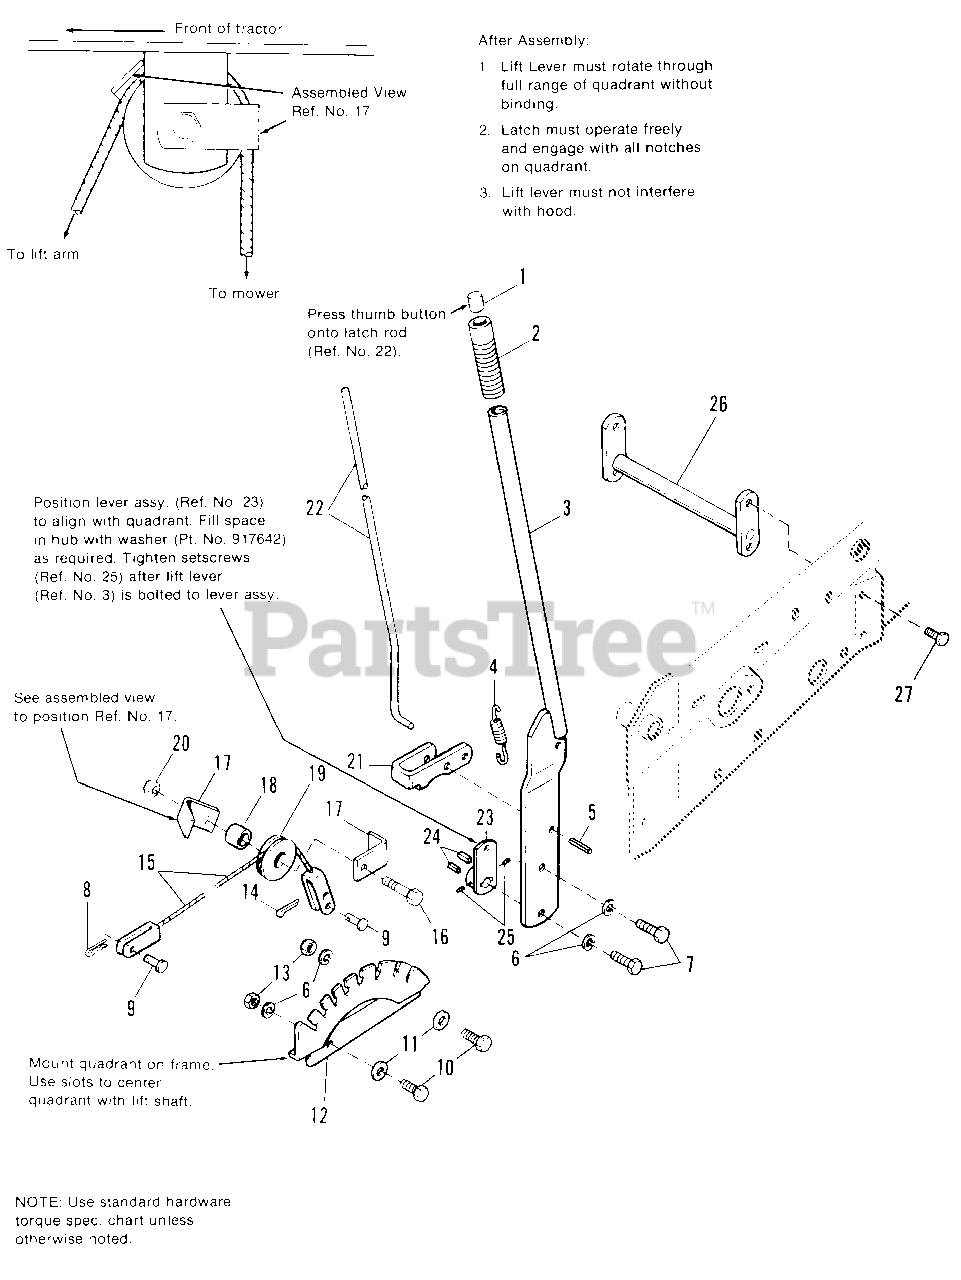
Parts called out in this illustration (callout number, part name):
2	GRIP
3	LEVER ASSY., Lift
5	PIN, Spring, 3/8 x 1-1/4
6	LOCKWASHER, 3/8
7	CAPSCREW, Hex Hd., 3/8-16 x 1
8	CLIP, Spring
10	CAPSCREW, Hex Hd., 3/8-16 x 7/8
11	WASHER, Plain, 5/16
13	NUT, Hex, Full, 3/8-16
14	PIN, Cotter, 3/32 x 3/4
15	CABLE ASSY., Lift
16	SCREW, Special
17	GUARD, Cable
20	LOCKNUT, Hex, Jam, 3/8-16
21	LATCH, Lift Lever
22	ROD LATCH
23	LEVER ASSY., Lift
25	SETSCREW, 5/16-18 x 1/4
26	SUPPORT ASSY.
27	SCREW, Self-Tapping, 3/8 x 3/4
